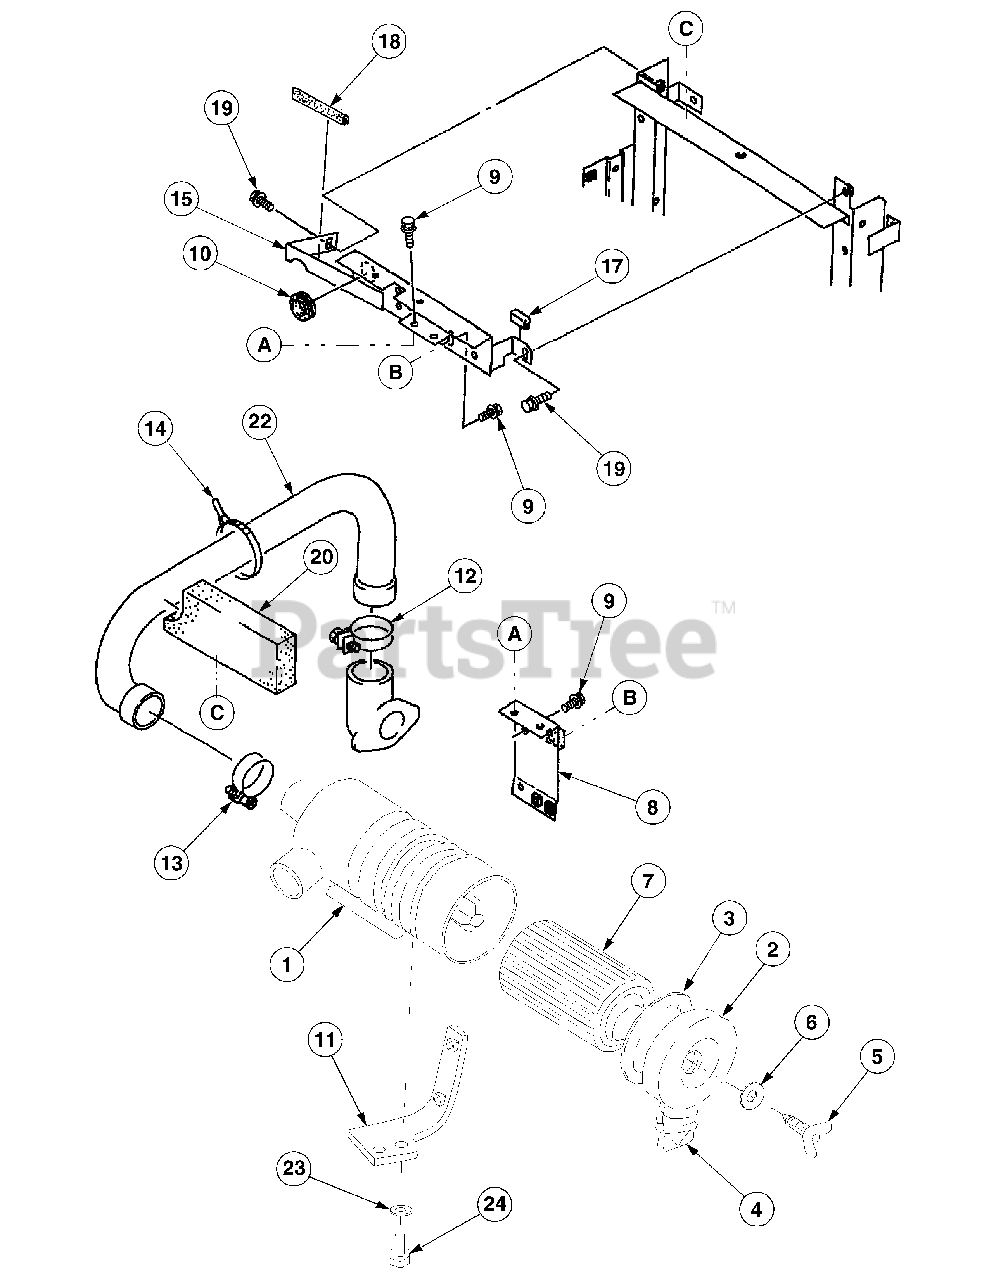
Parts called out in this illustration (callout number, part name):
1	Case Assy
4	Valve, Unloader
8	Bracket, Cleaner
9	Bolt, w/Washer
19	Bolt, w/Washer
22	Hose, Air Cleaner
